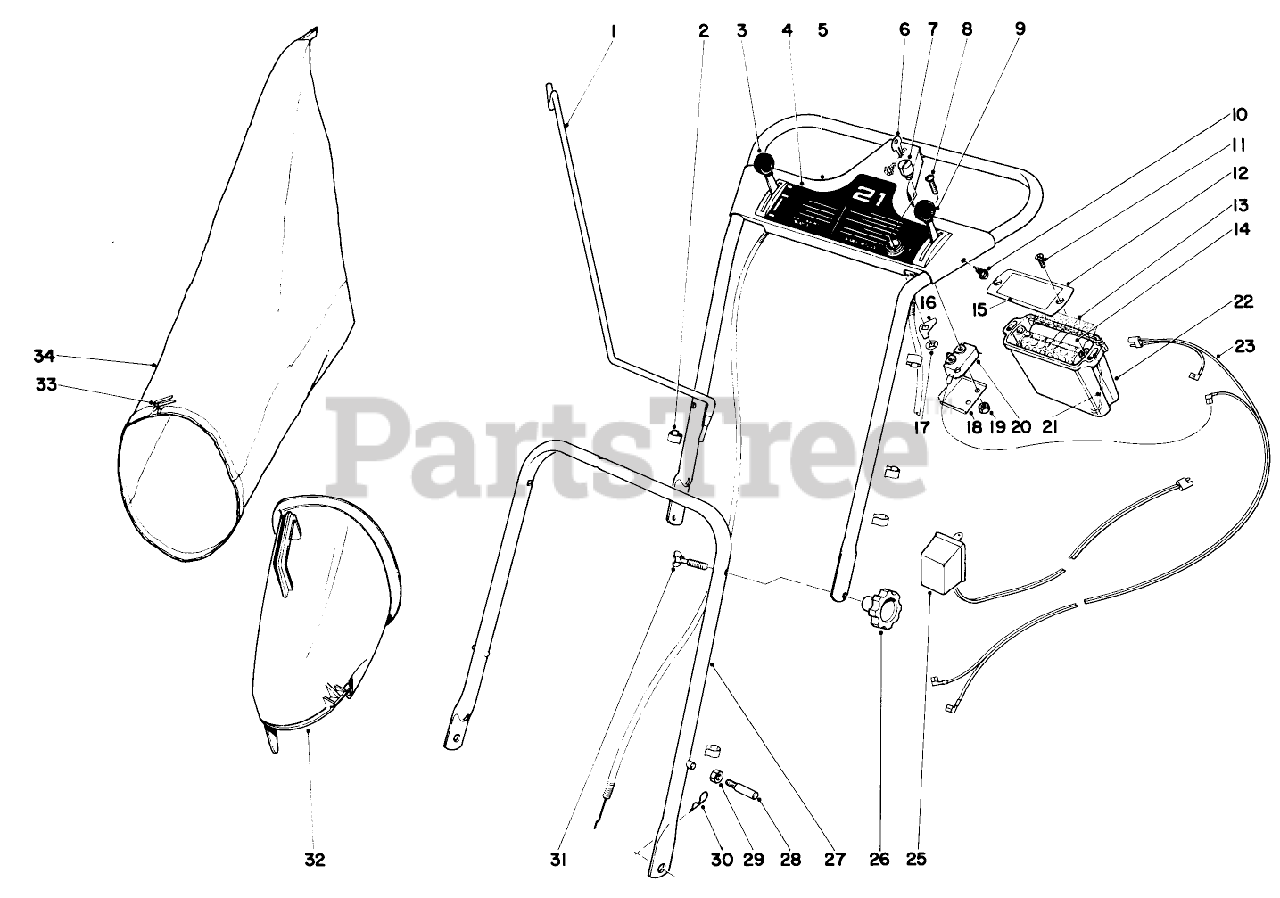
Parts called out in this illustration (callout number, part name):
4	Decal, Escutcheon Plate
5	Escutcheon Plate
7	Key Hsg.
10	SCREW-HWHTF
15	Decal
18	Cover Switch
19	NUT, HEX
20	Switch
24	Upper Handle
27	Lower Handle
30	PIN-COTTER, HAIR
33	BAG CORD FASTENER
